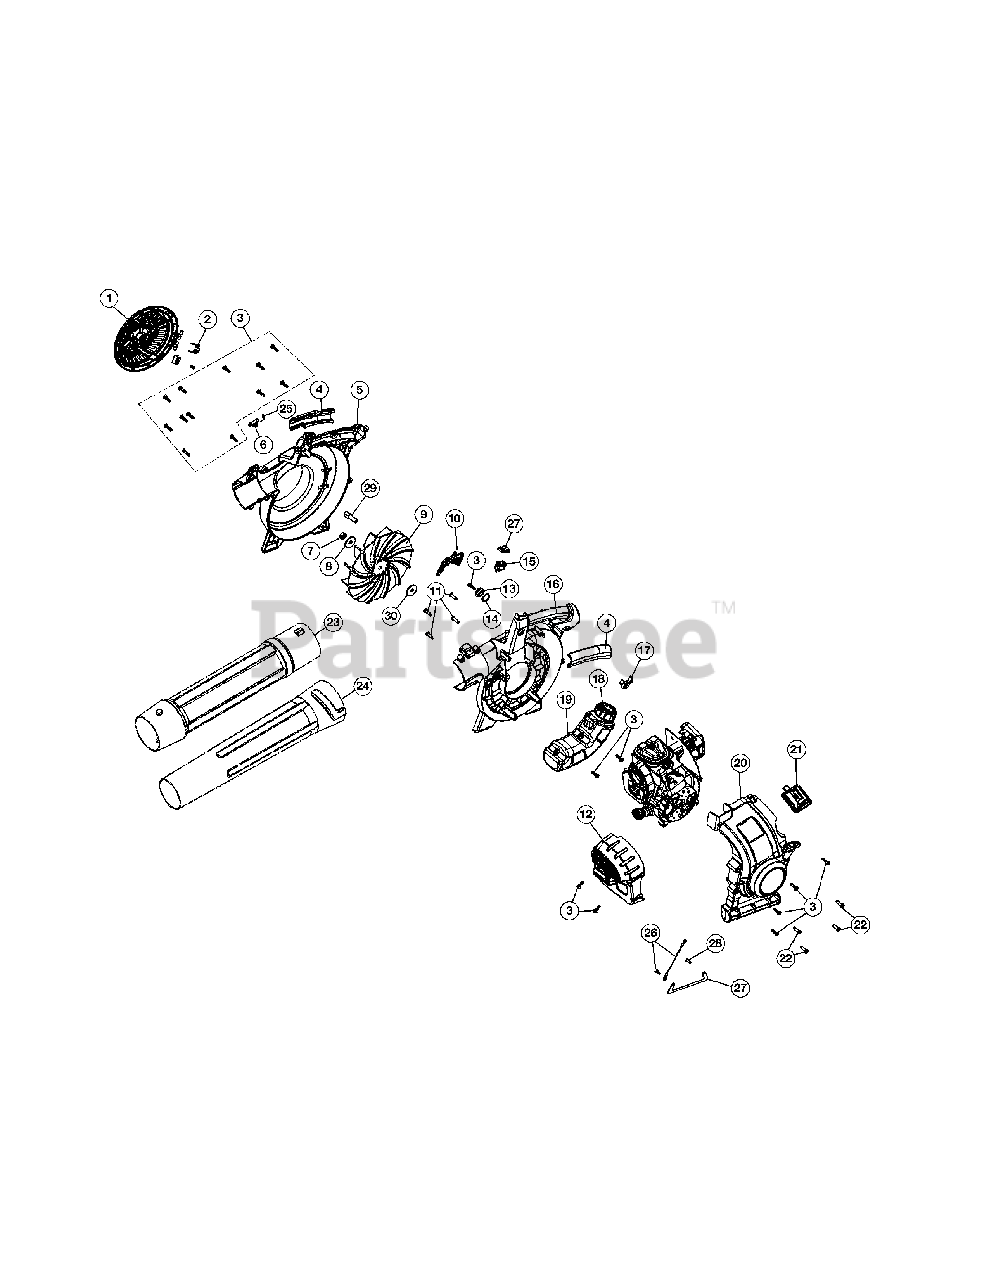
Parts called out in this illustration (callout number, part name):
1	Intake Cover Assembly
4	Handle Grips
5	Impeller Housing (Incl. 4)
6	Latch Tube
10	Throttle Trigger
11	Screw
12	Muffler Cover (Incl. 3)
13	Inner Trigger Lock
14	Wavey Washer
16	Impeller Housing (Incl. 4)
17	Outer Trigger Lock
19	Fuel Tank Assembly (Incl. 18)
20	Engine Cover Assembly (Incl. 3, 21 & 22)
21	Spark Plug Cover
23	Upper Tube
24	Lower Tube
25	Latch Spring
26	Wire Ground
27	Strap Ground
28	Screw
